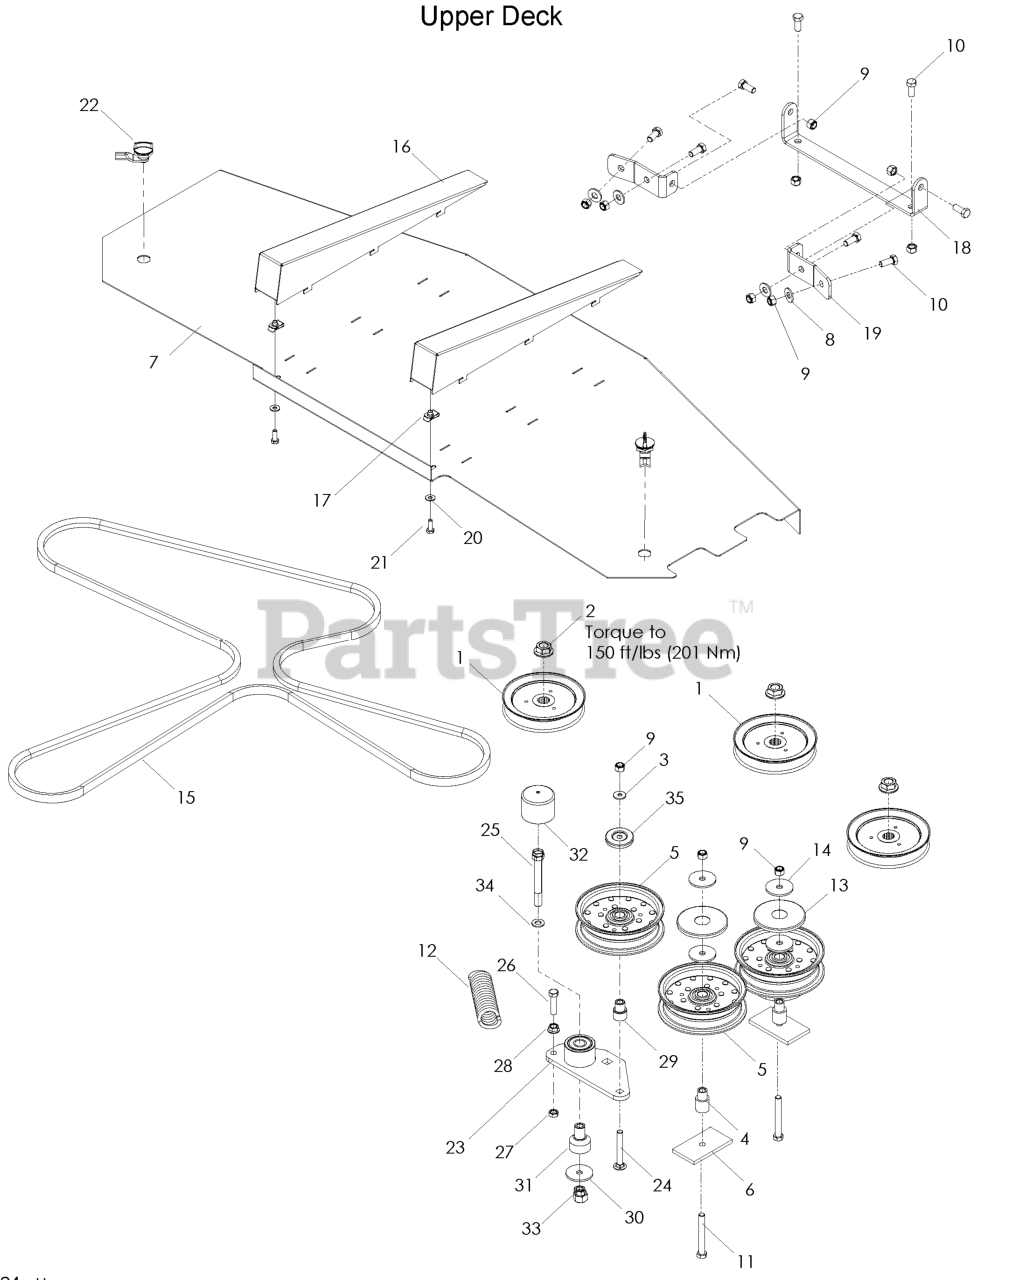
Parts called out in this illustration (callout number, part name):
1	PULLEY - 6.57
2	NUT FLANGE 3/4-16
3	WASHER, 3/8 THICK
4	IDLER BUSHING
5	IDLER PULLEY
6	SUPPORT PLATE
7	COVER - BELT, 52 PAINTED
8	WASHER 3/8 FLAT
9	NUT 3/8-16 NYLOC
10	HCS 3/8-16 X 7/8 GR 5 ZD
11	HCS 3/8C X 3
13	TOP DUST CAP
14	WASHER, 3/8 SPEC
15	V-BELT 142
16	WEDGE - PAINTED
17	1/4C - U TYPE RETAINER
18	HINGE, BIN
19	BASE HINGE - PAINTED
20	WASHER 1/4 SAE
21	HCS 1/4C X 3/4 HCS
22	LATCH, SHORT WING
23	ARM-IDLER W/BRG
24	RHSNB 3/8-16 X 2.75
25	HCS 1/2C X 3 1/4
26	HCS 3/8-16 X 1-1/2
27	NUT 3/8-16 HEX JAM
28	NUT 3/8C WHIZ
29	BUSHING, IDLER
30	WASHER, SUPPORT
31	PIVOT, BEARING
32	CAP, VINYL
33	NUT 1/2-13 HEX NYLOC ZD
34	CONTACT BELLSPR 1/2
35	DUST SHIELD
